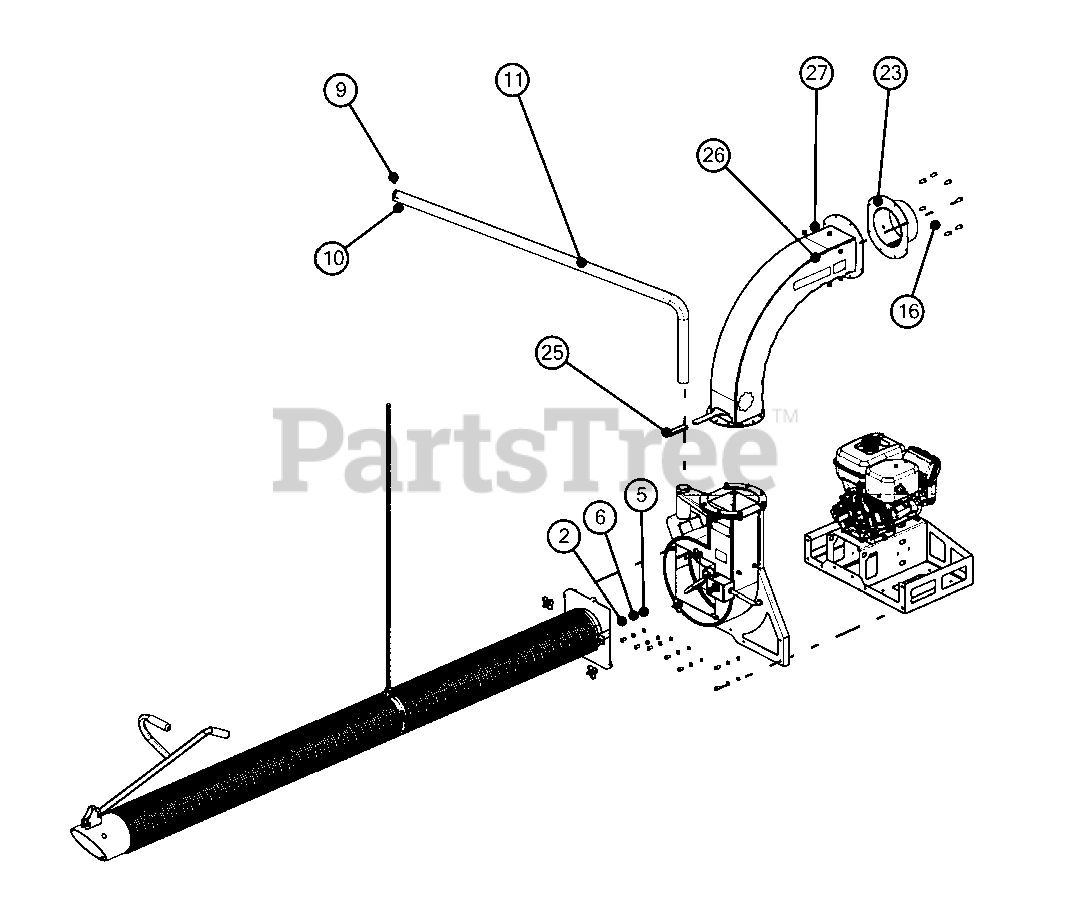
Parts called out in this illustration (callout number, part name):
2	Bolt, Hex .31-18 x .75 Grade 5 YWZC
5	Washer, Lock .31 x .078 Reg YWZC
6	Washer, Flat .344 x .688 x .065 Stl, YWZC
9	Bolt, Hex .25-20 x 2.50 Grade 5 YWZC
10	Nut, .25-20 Nyloc Flange
11	Support Arm
16	Bolt, Hex .31-18 x 1.00 Grade 5 YWZC
23	Weldment, Discharge 8"
25	Grip, Rubber Lever
26	Assy, Exhaust Tall W/Decals (Grn)
27	Nut, .31-18 Nyloc Flange YXZC
